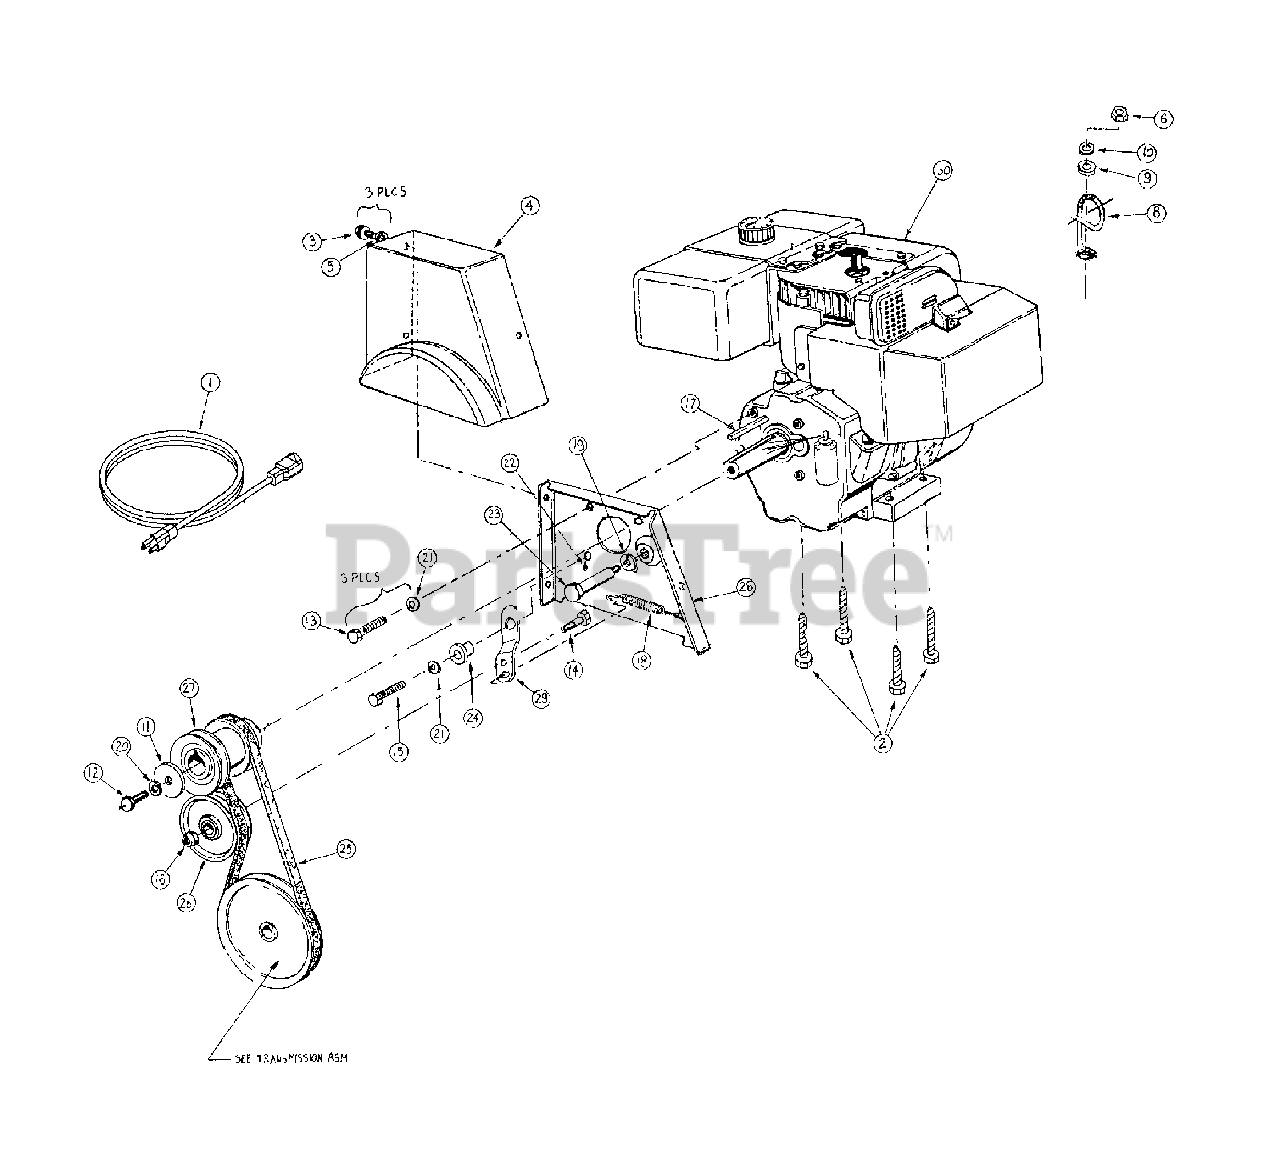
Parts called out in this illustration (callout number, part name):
1	Extension Cord 10 Ft.
2	Hex L-wash Tt Scr 3/8-16 X 1.25
3	Hwhd 5/16-18 X 1/2 Thd Roll Zn
4	Belt Cover - Pierced
5	Fl-wash .344 ID X .625 OD X .063
6	Nut 1/4-20 GR B Hex
8	Cable Control Wire
9	Fl-Wash .28 ID x .74 OD x .063
10	Lock Washer 1/4
11	Wash .39 ID X 1.75 OD X .175 T
12	Scr Hex Cap 3/8-24 X 1. Gd 8
13	Scr Hex Cap 5/16-24 X .62 Gd 5
14	Scr Hex Cap 3/8-24 X 1.5 Gd 5
15	Hhcs 5/16-24 X 7/8 Gr 5
16	Hex Ins L-nut 3/8 - 24
17	Square Key 1/4 X 1.5
18	Extension Spring .38 OD X 3.18 L
19	L-wash 3/8
20	Lock Washer 3/8 Heavy
21	Bell Wash .345 ID X .88 OD X .060
22	Grease - Sunaplex 781 - 1/10
23	Shoulder Scr .498 Dia X 3.0 Lg
24	Shldr Spcr .50 Dia X .14 Shldr
25	3v Belt 35.5 Lg
26	3.0 OD Flat Idler With Flange
27	Dbl Engine Pulley 3.25 & 2.75
30	Engine
